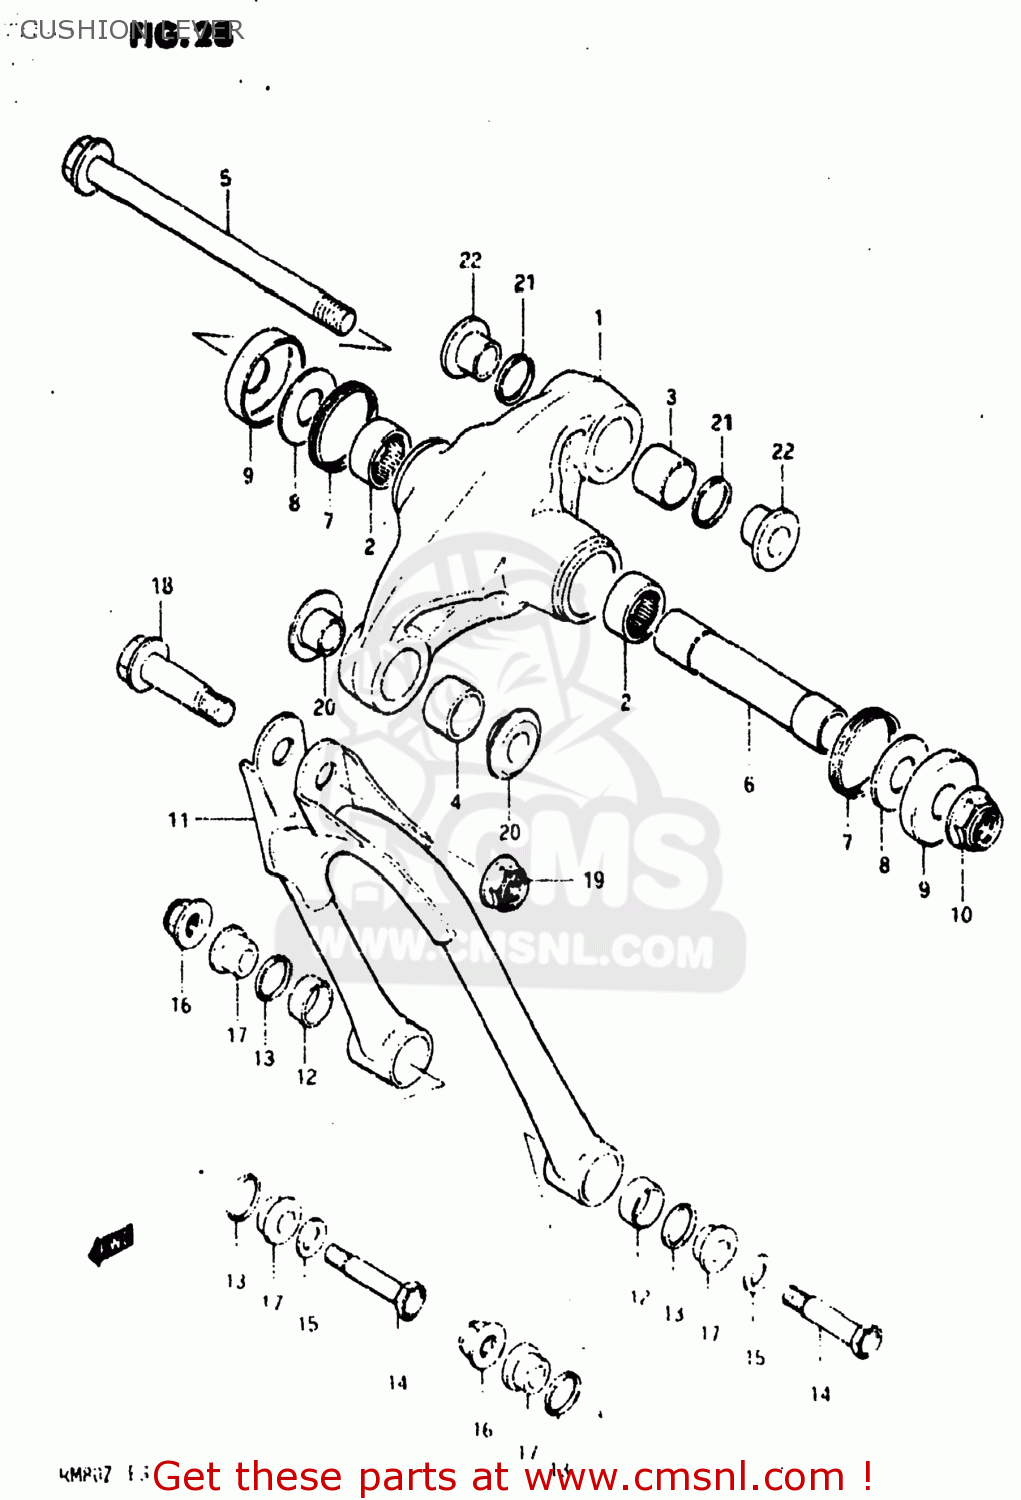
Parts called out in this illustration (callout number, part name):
1	LEVER SET,REAR CUSHION
2	BEARING(17X25X20)
3	BUSH,LEVER CUSHION UNIT
4	BUSH, FRONT
5	SHAFT,REAR CUSHION LEVER
6	SPACER,REAR CUSHION LEVER
7	DUST SEAL,RR CUSHION LEVER
8	THRUST WASHER
9	DUST COVER,REAR CUSHION
10	NUT 12MM
11	LEVER SET,REAR CUSHION
12	BUSHING
13	DUST SEAL,RR CUSHION LOD LWR
14	BOLT,REAR CUSHION LEVER
15	WASHER
16	NUT
17	SPACER,RR CUSHION ROD LWR
18	BOLT(10X40)
19	NUT
20	SPACER,REAR CUSHION,FRONT
21	DUST SEAL,LEVER CUSHION UNIT
22	SPACER,LEVER CUSHION UNIT
